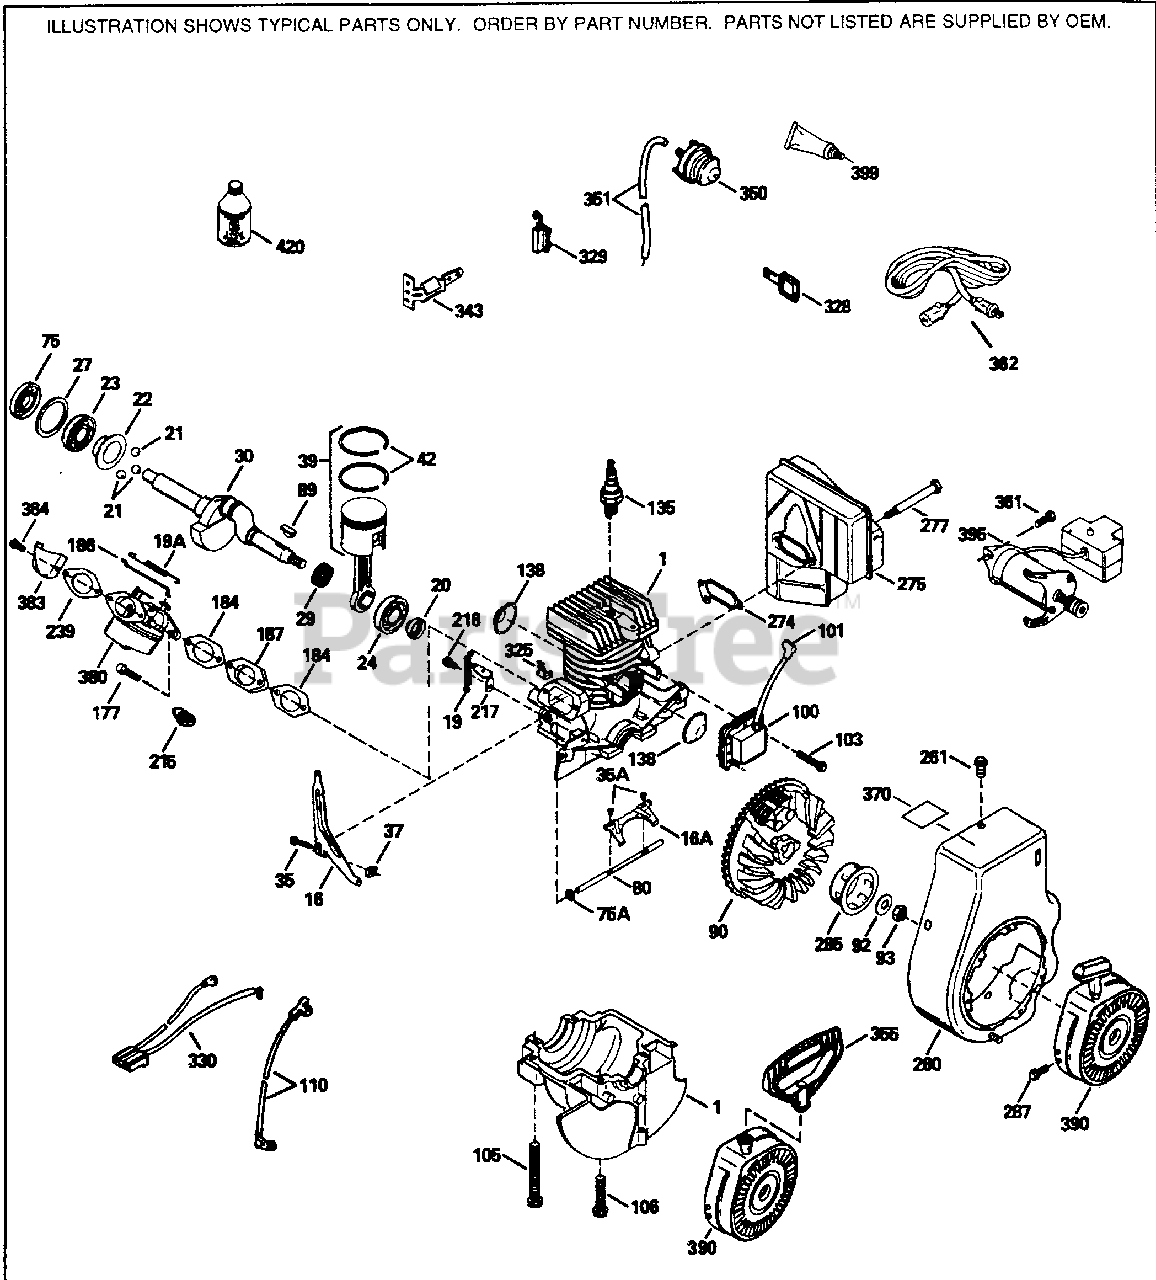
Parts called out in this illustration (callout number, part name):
1	"Cylinder Ass'y. (Incl. 75A, 138, 105, 106)& 138)
1	Cylinder (Incl. 2, 20, 72 & 80) (3-5/ 16" Bore)
2	Dowel Pin
14	Flat Washer
15	Governor Rod (Incl. 14 & 38)
16	Governor Lever
16A	Governor Follower Arm
17	Governor Lever Clamp
19	Extension Spring
19A	Throttle Link Spring
20	Oil Seal
21	Ball Bearing
22	Slide Ring
23	Ball Bearing
24	Ball Bearing
27	Bearing Retainer
29	Bearing Strip (31 Needles)
30	Crankshaft
31	Counterbalance Gear
35	Screw, 10-32 X 3/4"
35	Screw, 10-32 x 3/4"
35A	Screw, 4-40 x 1/4"
37	Lock Nut, 10-32
38	Retaining Ring
39	Piston & Rod Ass'y. (Incl. 29 & 42)
40	Piston, Pin & Ring Set (Std.)
42	Ring Set
43	Piston Pin Retaining Ring
45	Connecting Rod Assembly (Incl. 47 & 4 9)
47	Connecting Rod Bolt (1/4-20 X 1-5/16" )
48	Valve Lifter
50	Camshaft (MCR)
51	Counterbalance Weight
69	Cylinder Cover Gasket
70	Cylinder Cover
71	Crankshaft Bushing
72	Oil Drain Plug (Sq. Hd., 1/4-18)
75	Oil Seal
75A	Oil Seal
80	Governor Shaft
81	Washer
82	Governor Gear Assembly
83	Governor Spool
84	Retaining Ring
86	Screw, 1/4-20 X 1-3/16"
87	Screw, 1/4-20 X 1- 11/16"
89	Flywheel Key
90	Flywheel
92	Belleville Washer
93	Flywheel Nut
100	Solid State Ignition
101	Spark Plug Cover
103	Screw. Torx T-15, 10-24 x 1"
105	Screw, 5/16-18 x 2-3/16"
106	Screw, 5/16-18 x 1-5/8"
119	Cylinder Head Gasket
135	Resistor Spark Plug (RCJ8Y)
138	Port Cover
159	Rocker Arm Cover Gasket
161	Screw, T-30, 1/4-20 x 1/2"
169	Valve Cover Gasket
170	Breather Body
171	Breather Element
172	Valve Cover
174	Screw, 10-24 X 1/2"
177	Screw, 5/32 Allen, 1/4-20 x 1"
184	Carburetor Gasket
184	Carburetor-To-Intake Pipe Gasket
186	Governor Link
217	Control Lever
218	Screw, 8-32 x 1/2"
224	Intake Pipe Gasket
239	Air Filter Gasket
260	Blower Housing
261	Screw, 5/16-18 x 5/8"
269	Exhaust Manifold Gasket
274	Exhaust Gasket
275	Muffler
277	Screw, 5/16-18 x 3-13/64"
285	Starter Cup
287	Screw, 8-32 x 21/64"
325	Wire Clip
330	Wire Harness
350	Primer Ass'y.
351	Primer Line
362	Extension Cord
370	Caution Decal
380	Carburetor (Incl. 184)
383	Spit Cup
384	Screw, Torx T-25, 10-32 x 3/8"
390	Rewind Starter
395	Electric Starter Motor (110 Volt)
399	Gasket Eliminator (Loctite 515)
420	2-Cycle Oil with Fuel Stabilizer - 8 oz.
